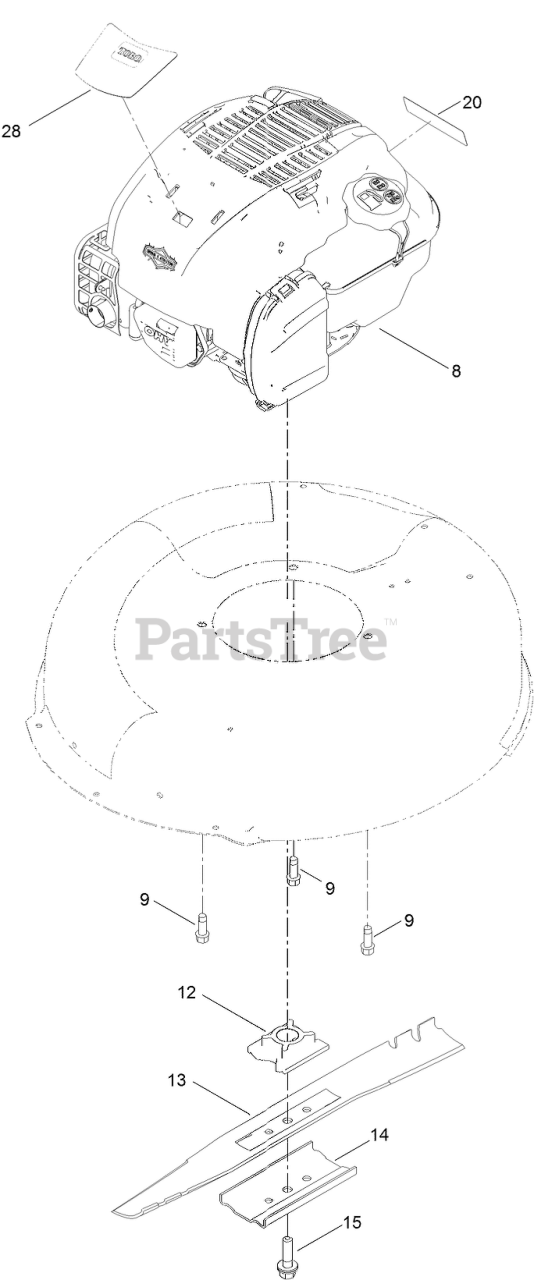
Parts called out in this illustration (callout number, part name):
9	SCREW-TAPTITE
12	RETAINER-BLADE
13	BLADE-21IN
14	SUPPORT-BLADE
15	BOLT-BLADE
20	DECAL-ARRESTOR, SPARK
28	DECAL-ENGINE
